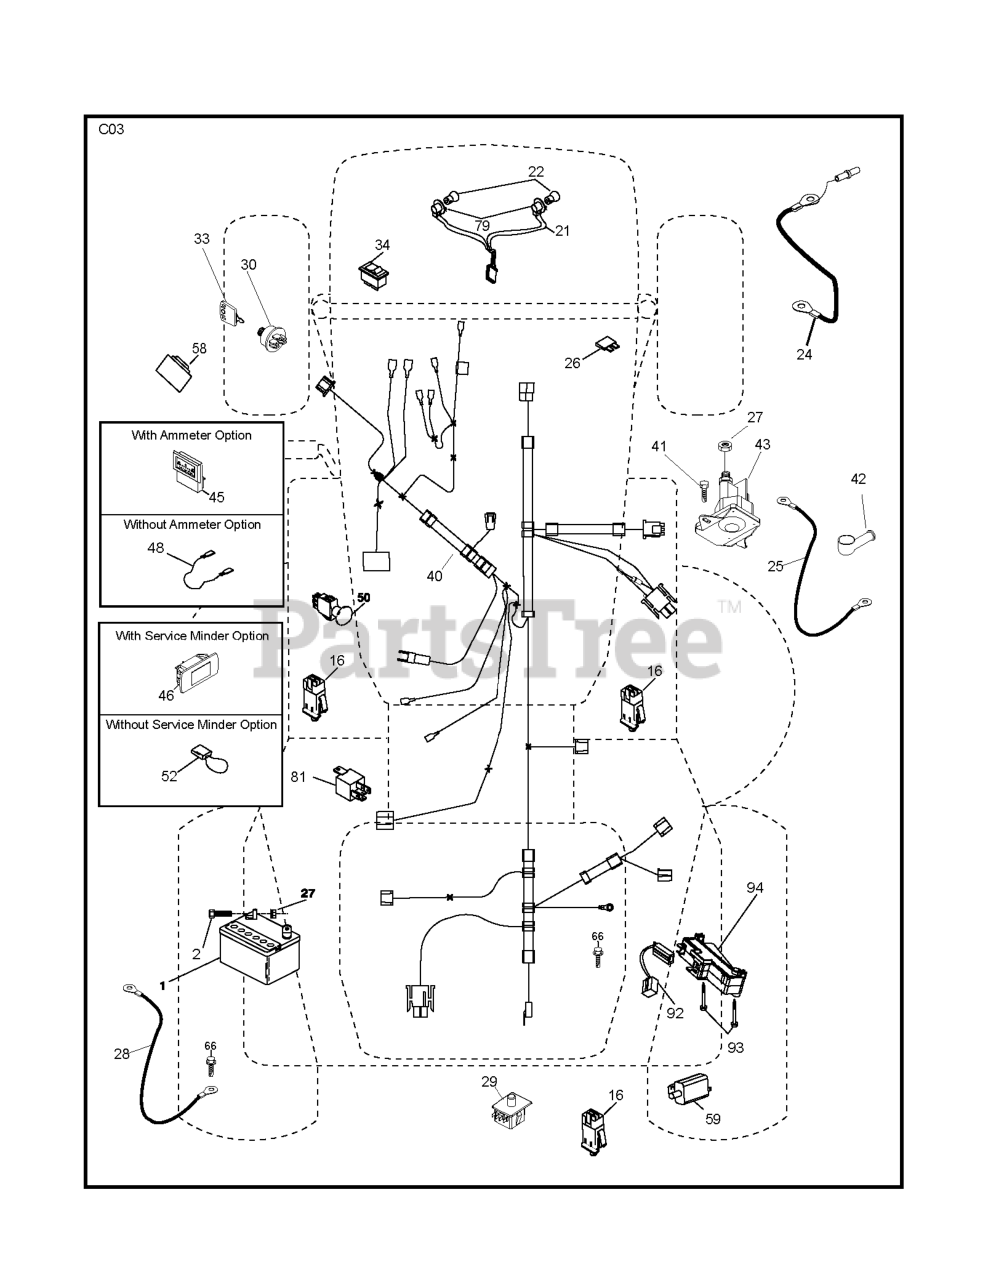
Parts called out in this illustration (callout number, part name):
1	Battery 12 Volt 25 Amp
2	BOLT.HEX.1/4.X.3/4.DICHROMATE
16	SWITCH INTERLOOK PUSH-IN
21	HARNESS.LIGHT W/4152J BULBS
24	BATTERY CABLE GT
25	CABLE BATTERY
26	FUSE 20AMP
27	NUT
28	CABLE GROUND
29	SWITCH.SEAT.DP W/RAMPS
30	SWITCH.IGN.DELTA.W.LGH.ROS
33	KEY.CHAIN.BLISTER.PACK.GEN.INT
40	RP HARNESS.IGN.ELECT.REG.CRD
41	BOLT
42	TERMINAL COVER
43	SOLENOID.W/BRASS.PLUNGER
48	ADAPTER.AMMETER
50	RP.PTO.SWITCH.8 TERMINAL.BLACK
52	WIRE PROTECTION LOOP
58	BUZZER
59	.WITCH.FULL BAGGER.INDICATOR
79	BULB HOLDER ASM.
81	RELAY.ASSY.T
92	HARNESS.PIGTAIL.CONSLE
93	SCREW.PLASTITE
94	MODULE.REVERSE.ROS
